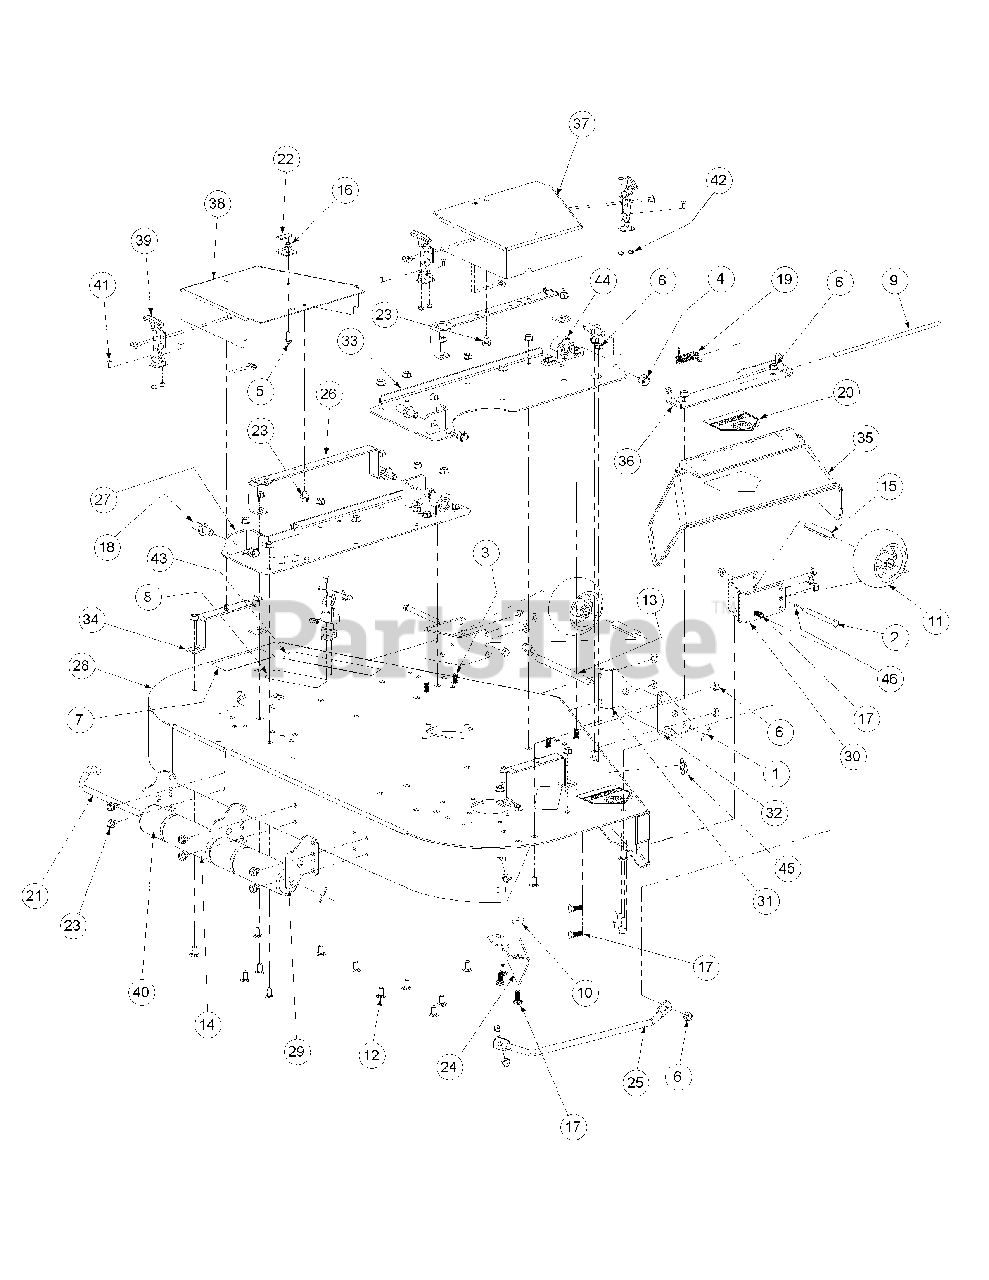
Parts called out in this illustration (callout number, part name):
1	Cotter Pin, .125 Dia. x 1.0
2	Hex Cap Screw, 3/8-16, 3.75
3	Carriage Screw, 3/8-16 x 1.25
4	Lock Nut, Nylon Insert, 1/2-13
5	Hex Cap Screw, 5/16-18 x 3/4
6	Flange Lock Hex Nut, 3/8-16
7	Decal Rotating Blade
8	Decal Warning Shield Missing
9	Chute Deflector Rod
10	Idler Washer
11	Complete Wheel, 5.00 Dia
12	Carriage Bolt, 3/8-16 x .75 Lg
13	Roller Pin, 1/2 Dia x 7.31 Lg
14	Front Roller
15	Wheel Spacer
16	Hex Flange Lock Nut, 5/16-18
17	Carriage Bolt, 3/8-16 x 1
18	Pin, 5/8 Dia. x 1.2 Lg.
19	Torsion Spring, 0.4 ID x 2.16 LG
20	Decal, Danger Hands and Feet
21	Roller Rod
22	Bracket Stop Tension Rod
23	Hex Index Washer Screw, 3/8-16, .05
24	Fabricated Deck, Chute Bracket
25	Fabricated Deck Finger Guard
26	Fabricated Belt Support Cover
27	Left Hand Deck Bracket Assembly
28	48 Fabricated Deck Assembly
29	Fabricted Deck Roller Mount Bracket
30	Front Anti-Scalp Wheel Mount Bracket
33	Right Hand Deck Bracket Assembly
34	Outer Belt Cover Support Assembly
35	Deflector Chute
36	Deflector Chute Bracket
37	Right Hand Belt Cover
38	Left Hand Belt Cover
39	Latch Drawing, T-Handle
41	Phillip Head Screw, 10-32
42	Lock Nut, Nylon Insert, 10-32
44	Pillow Block
45	Decal, 48"
46	Flat Washer, 3/8
